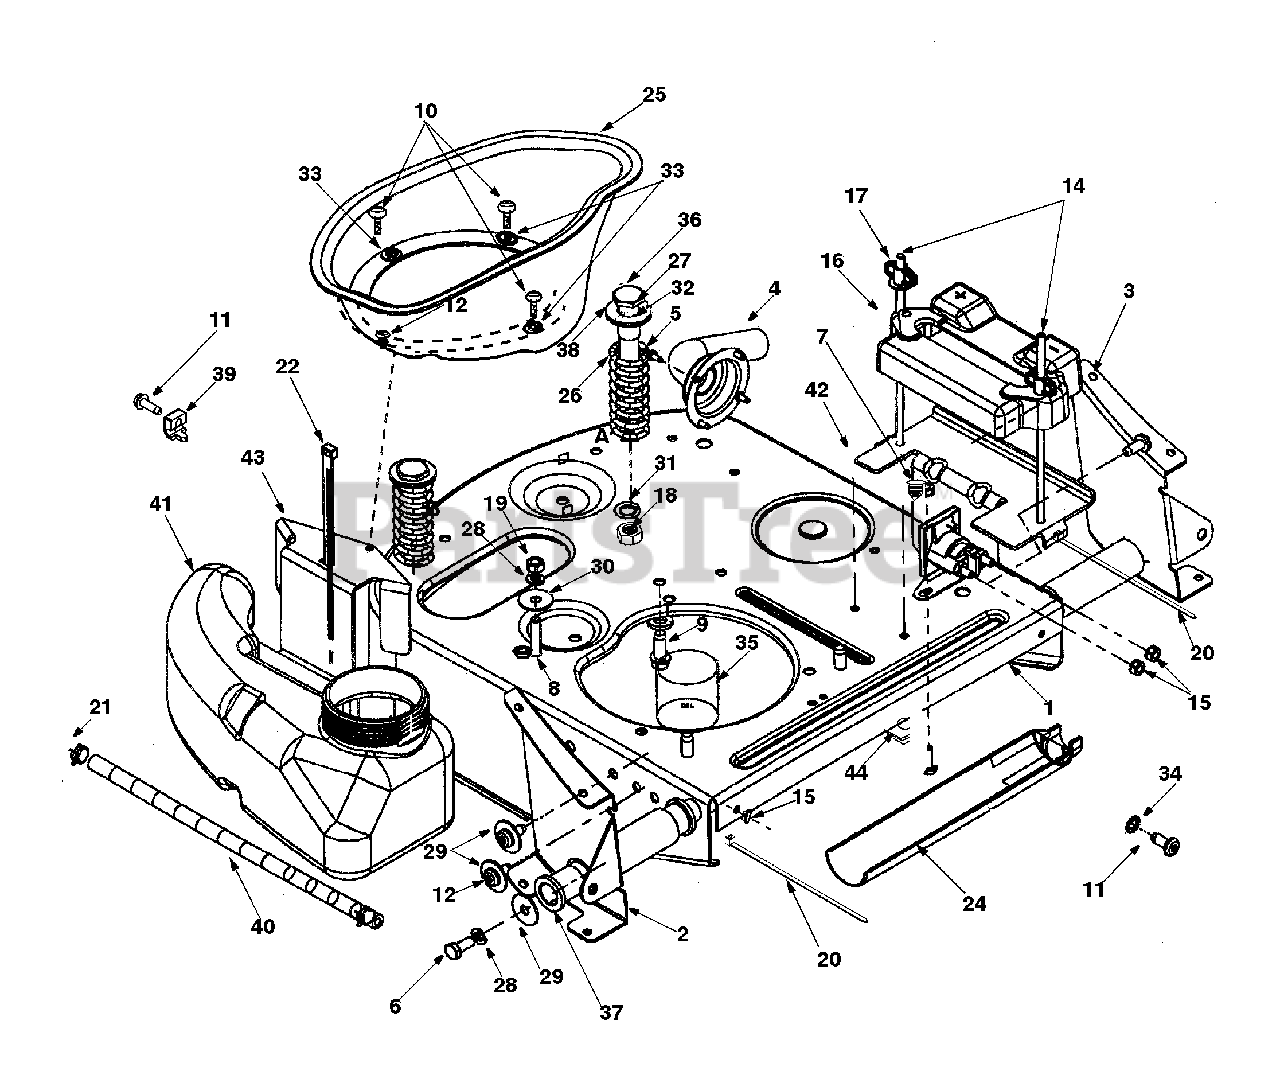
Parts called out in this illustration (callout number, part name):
5	Hex Fl. Screw #8-32 x 0.375
6	Hex Screw 5/16-24 x .75" Gr.5
7	Self-Tapping Screw
8	Hex Screw 5/16-24 x 1.5" Gr.5
9	Hex Washer Head TT Screw 3/8-16 x 1.0"
10	Hex Slot Sems Screw #10-32 x 0.38
11	Hex Washer TT Screw #10-32 x 0.625"
12	TT Screw 5/16-18 x 0.75"
14	Battery Hold-Down Rod
15	Hex Sems Nut 1/4-20
16	Lock Nut 1/4-20
17	Wing Nut with Bell Washer
18	Hex Nut
19	Hex Nut 5/16-24 Gr.5
20	Cable Tie
21	Hose Clamp
22	Cable Tie
24	Oil Drain Sleeve
25	Engine Duct
26	Compression Spring
27	Rubber Washer
28	Lock Washer
29	Flat Washer
30	5/16 Washer
31	Lock Washer
32	Flat Washer
33	Flat Washer
34	Lock Washer
35	Motor Oil
36	Shoulder Screw
37	Flange Bearing
38	Flange Bearing
39	Throttle Casing Clamp
40	Fuel Line Hose
41	Fuel Tank
